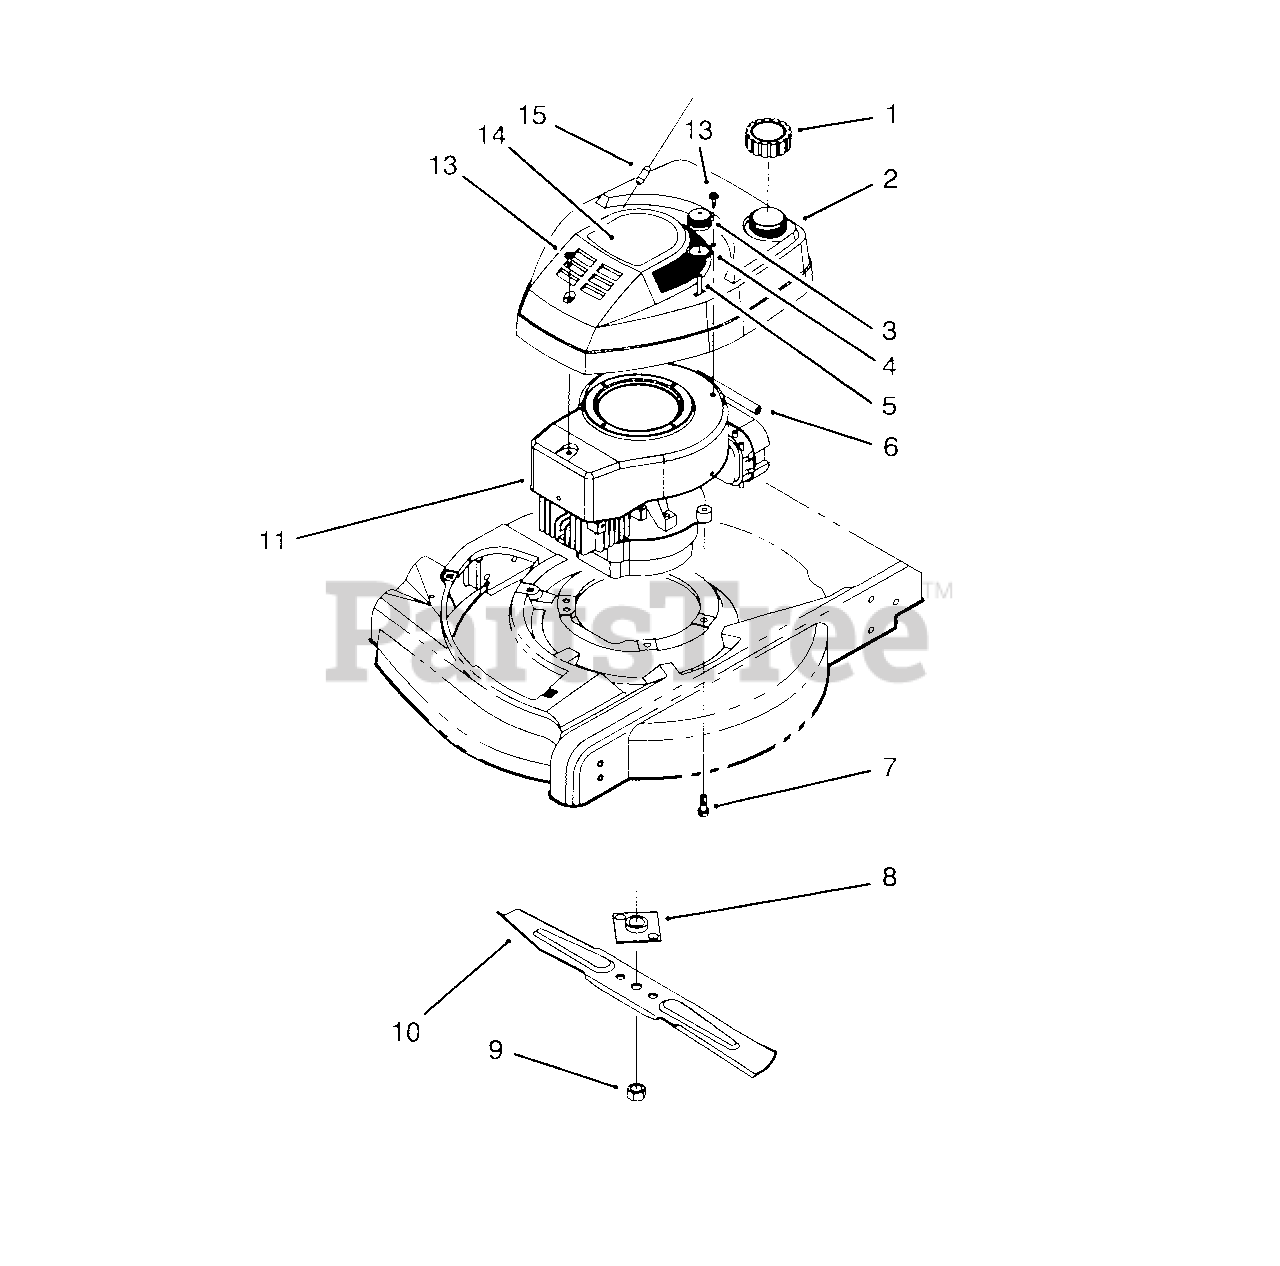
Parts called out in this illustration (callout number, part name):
1	Cap-Gas
2	Tank & Shroud Assembly
3	Bulb-Primer
4	Body-Primer
5	Hose-Primer
6	Line-Gas
7	Screw-Engine
8	Plate & Collar Assembly
9	Nut-Blade
10	Blade-21 "
11	Engine
13	Screw-Sems
14	Decal-Shroud
15	Rope-Stop
